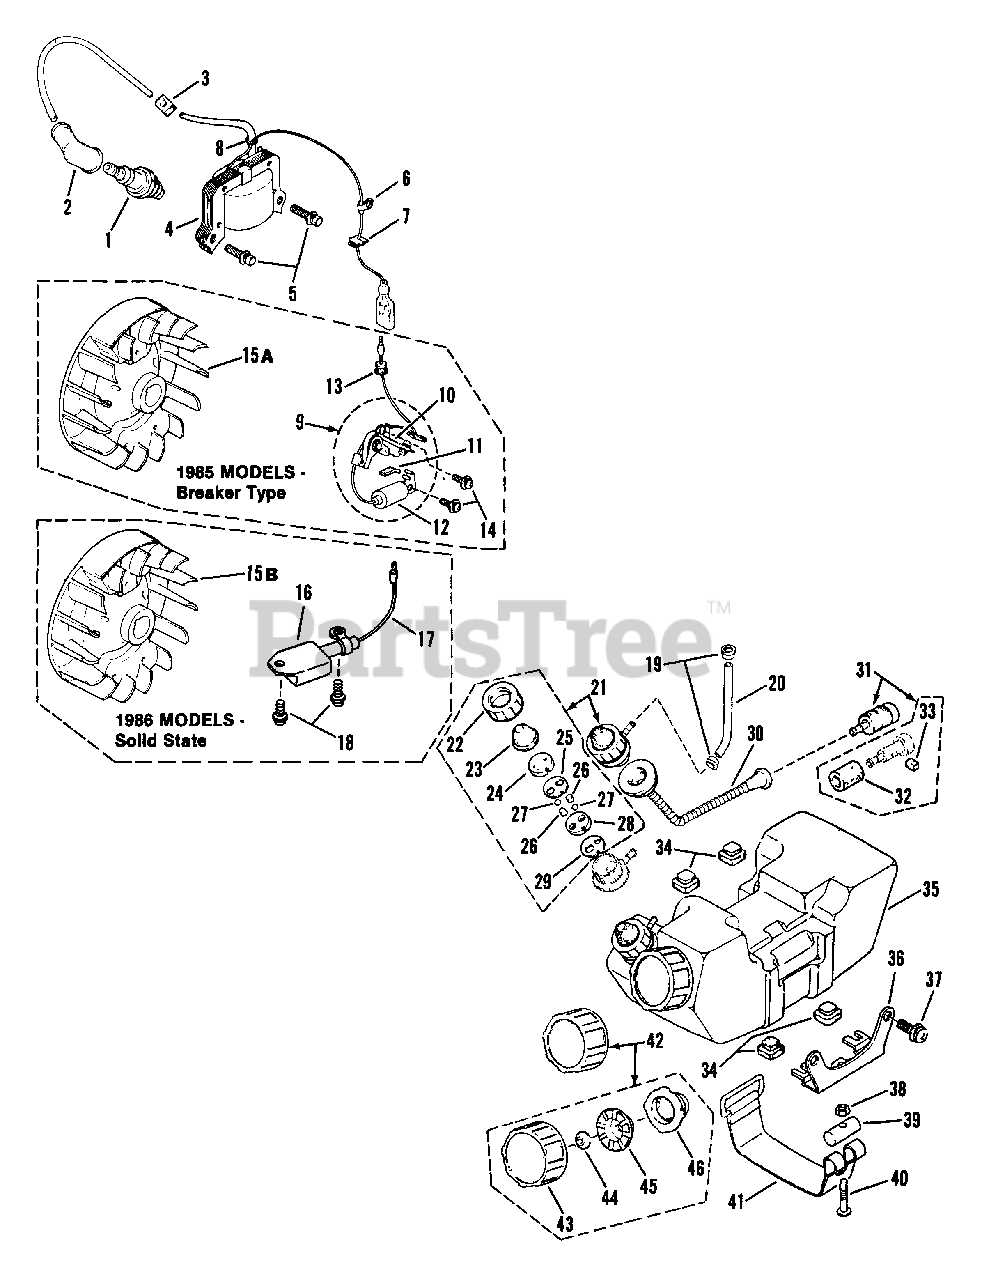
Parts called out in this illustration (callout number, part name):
1	SPARK PLUG (NGK: BM-6A)
2	BOOT, Spark Plug
3	BUSHING, Dust Seal
4	COIL, Ignition
7	BUSHING, Dust Seal
8	BAND
9	CONTACT BREAKER ASSM'Y.
10	CONTACT BREAKER (1985 only)
11	FELT, Oil (1985 only)
12	CONDENSER ASSM'Y.
13	BUSHING, Dust Seal
15A	FLYWHEEL (1985 Model)
15B	FLYWHEEL (1986 Model)
16	MTI Unit
17	WIRE, Lead
19	CLIP, Fuel Tube
20	TUBE, Fuel
21	PRIMER PUMP ASSM'Y.
22	CAP, Pump
23	CAP, Rubber
24	SEAT, Valve B
28	SEAT, Valve A
30	HOSE, Fuel
31	FILTER ASSM'Y., Fuel
35	TANK ASSM'Y.,Fuel
36	HANGER, Tank
37	SCREW, Hanger
39	BAR, Band Support
41	BAND, Tank
42	CAP ASSM'Y.,Fuel
43	CAP, Fuel
46	GASKET
